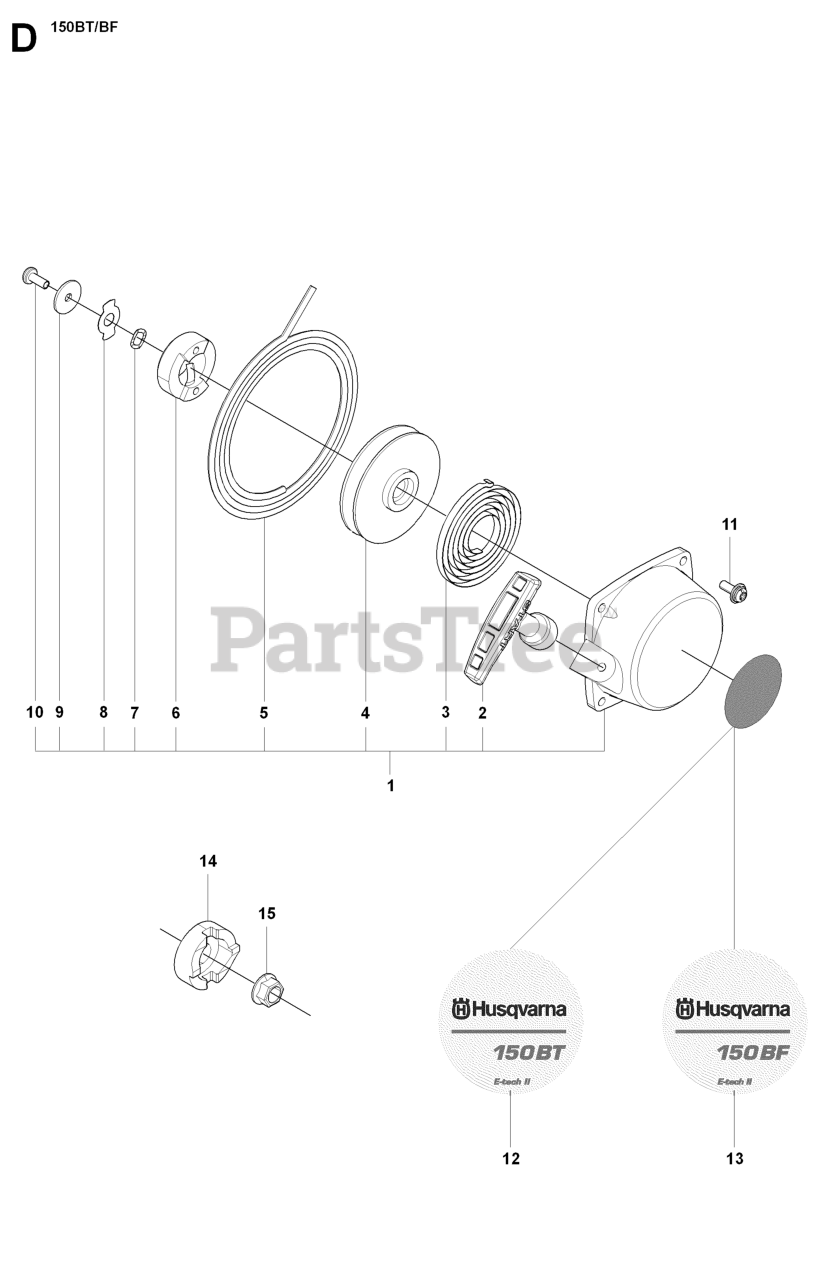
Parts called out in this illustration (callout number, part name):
1	STARTER ASSY
4	STARTER PULLEY
5	STARTER ROPE
6	STARTER PAWL
8	RETAINER
9	WASHER
13	STARTER PAWL
14	NUT
